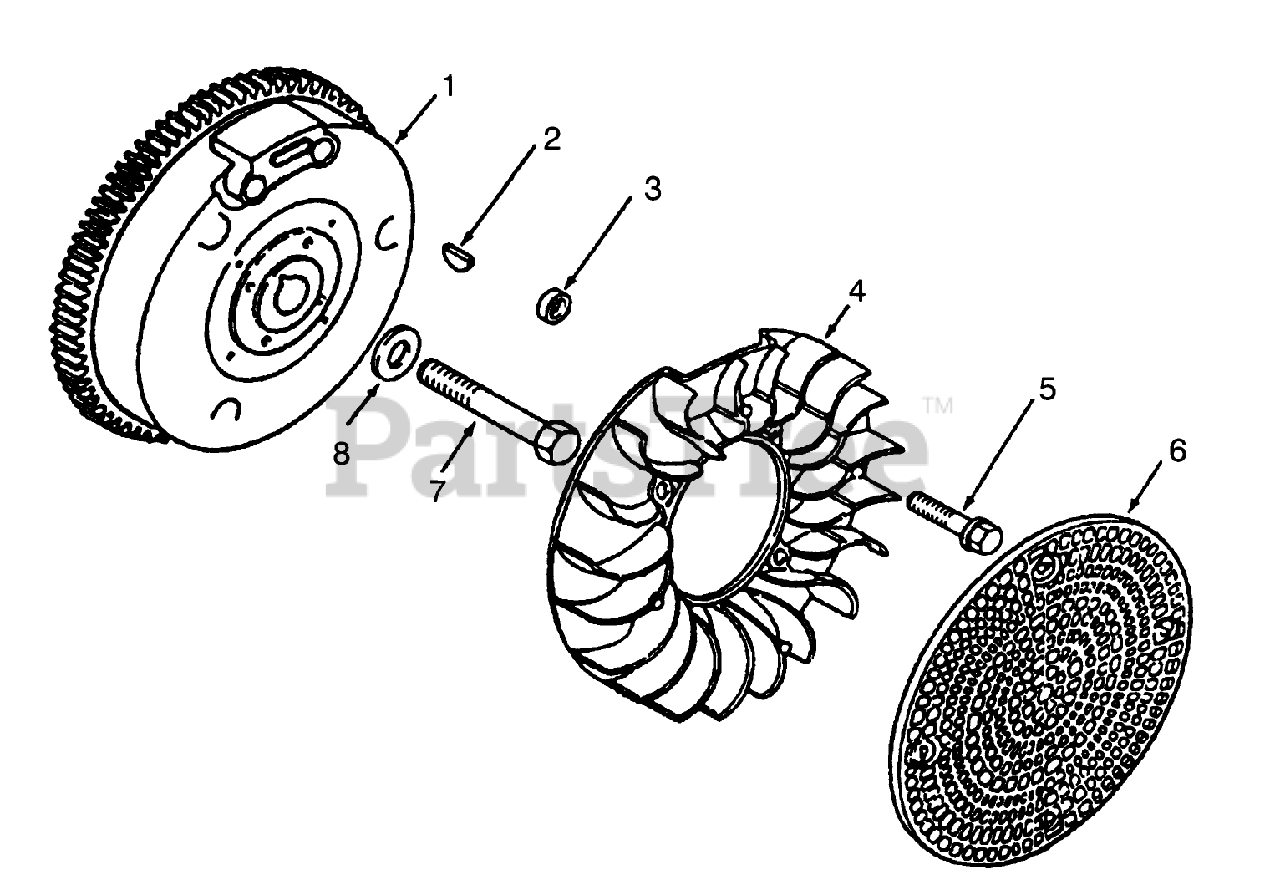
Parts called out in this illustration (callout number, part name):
1	KOHLER 47-025-53
2	KOHLER X-46-3
3	KOHLER 25-089-02
4	KOHLER 25-157-01
5	KOHLER 25-086-21
6	KOHLER 25-162-01
7	KOHLER 25-086-24
8	KOHLER 52-468-15
